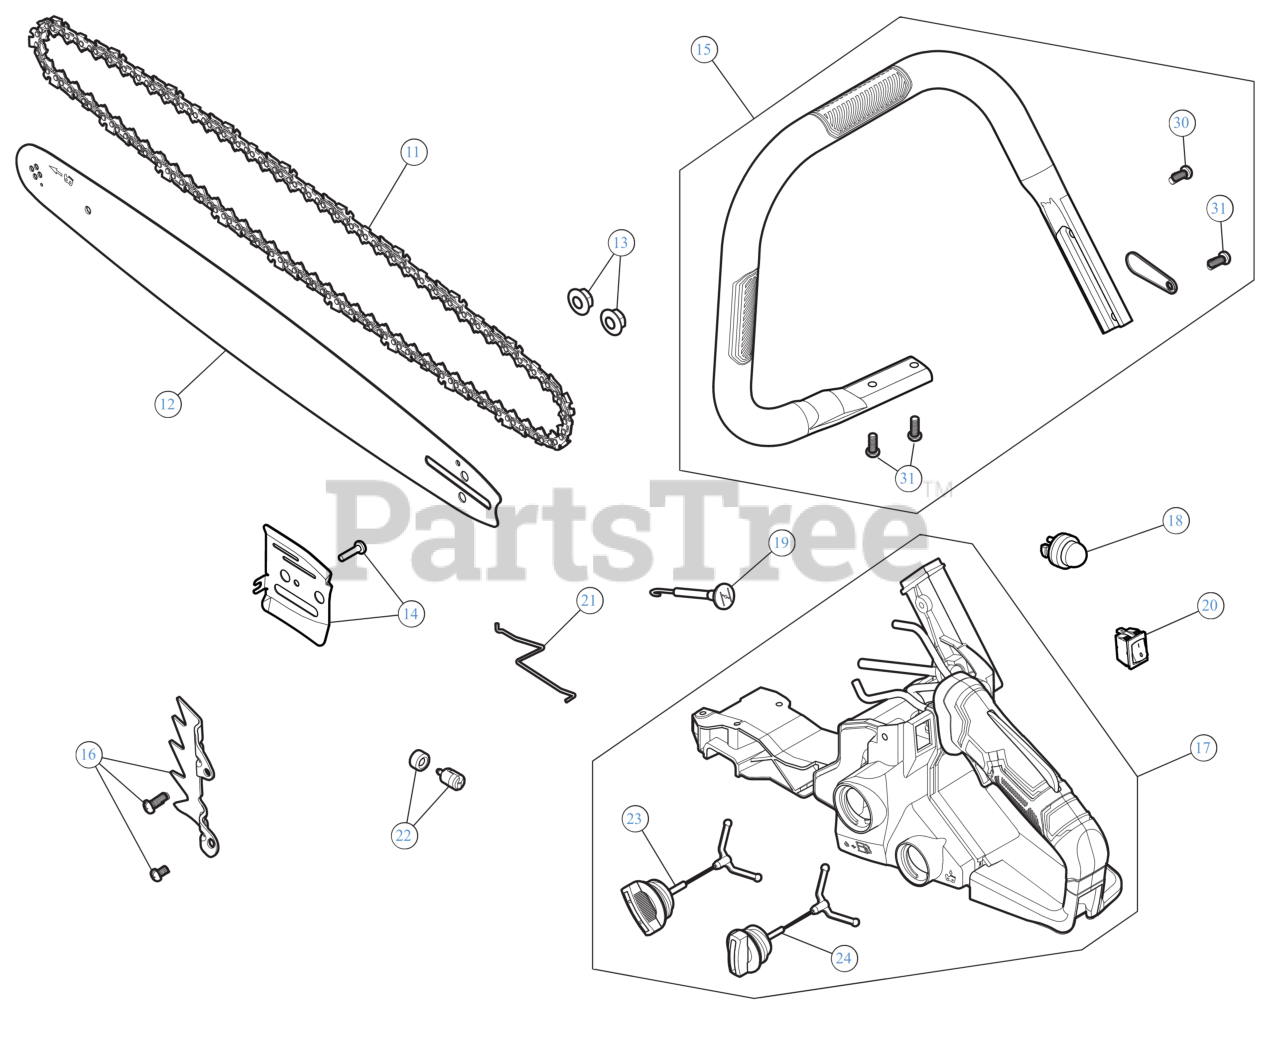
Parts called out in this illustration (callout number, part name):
11	14" CHAIN
11	16" CHAIN
11	CHAIN 18" TRILINK
12	14" GUIDE BAR
12	16" GUIDE BAR
12	18" GUIDE BAR
13	HEX FLANGE NUT
14	BAR PLATE
15	HANDLE
16	SPIKE PLATE
17	FUEL TANK
18	PRIMER BULB
19	CHOKE LEVER
20	SWITCH
21	THROTTLE ROD
22	FUEL FILTER
23	FUEL CAP
24	OIL CAP
